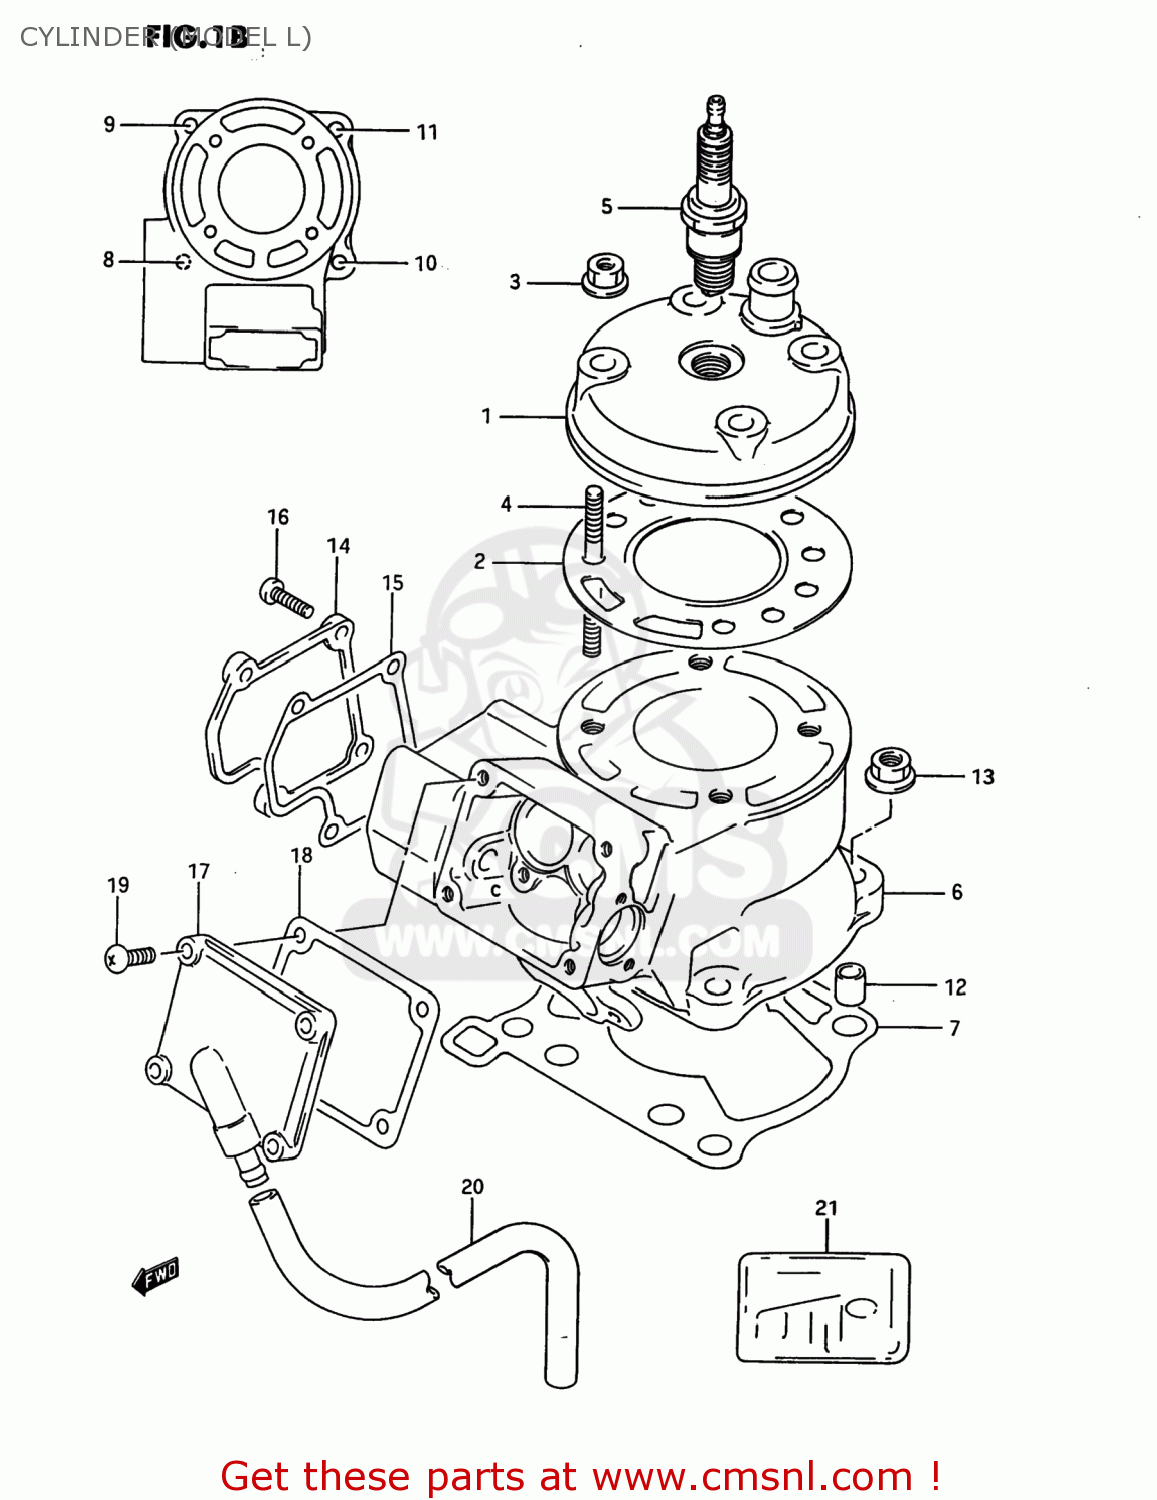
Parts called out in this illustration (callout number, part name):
1	HEAD,CYLINDER
2	GASKET,CYLINDER HEAD (NAS)
3	NUT
4	STUD
5	SPARK PLUG B9ES
6	CYLINDER
7	GASKET,CYLINDER (NAS)
8	BOLT,STUD
9	STUD 8X25
10	BOLT,STUD
11	BOLT,STUD
12	PIN
13	NUT
14	COVER,CYLINDER NO.1
15	GASKET,CYLINDER COVER NO.1 (NAS)
16	SCREW
17	COVER,CYLINDER
18	GASKET,CYL COVER NO.2 (NAS)
19	SCREW
20	HOSE (6.5X11.5X300)
21	GASKET SET (NAS)
